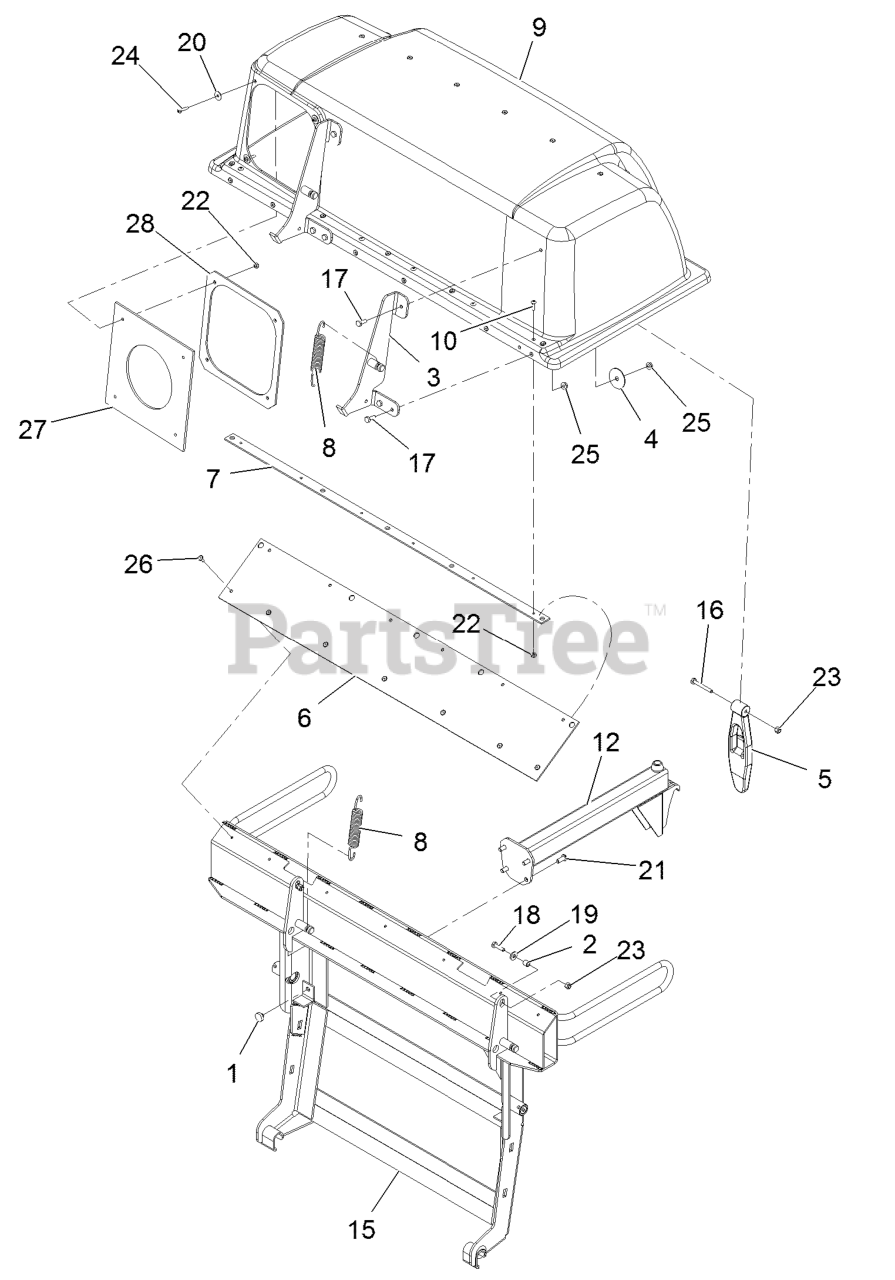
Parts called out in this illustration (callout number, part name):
3	HINGE ASM
7	PLATE-BACKING
8	SPRING-EXTENSION
9	ASM, HOOD
10	SCREW-HEAD, TRUSS
12	BAG SUPPORT ASM
15	FRAME-BAG, TWIN
16	SCREW-HH
17	SCREW-HH
18	SCREW-HH
19	WASHER-FLAT
20	WASHER-FLAT
21	SCREW-HSBH
22	NUT-LOCK, NI
23	NUT-LOCK, NI
24	SCREW-PPH
26	RIVET-BLIND
27	SEAL-CHUTE
28	CLAMP-SEAL
